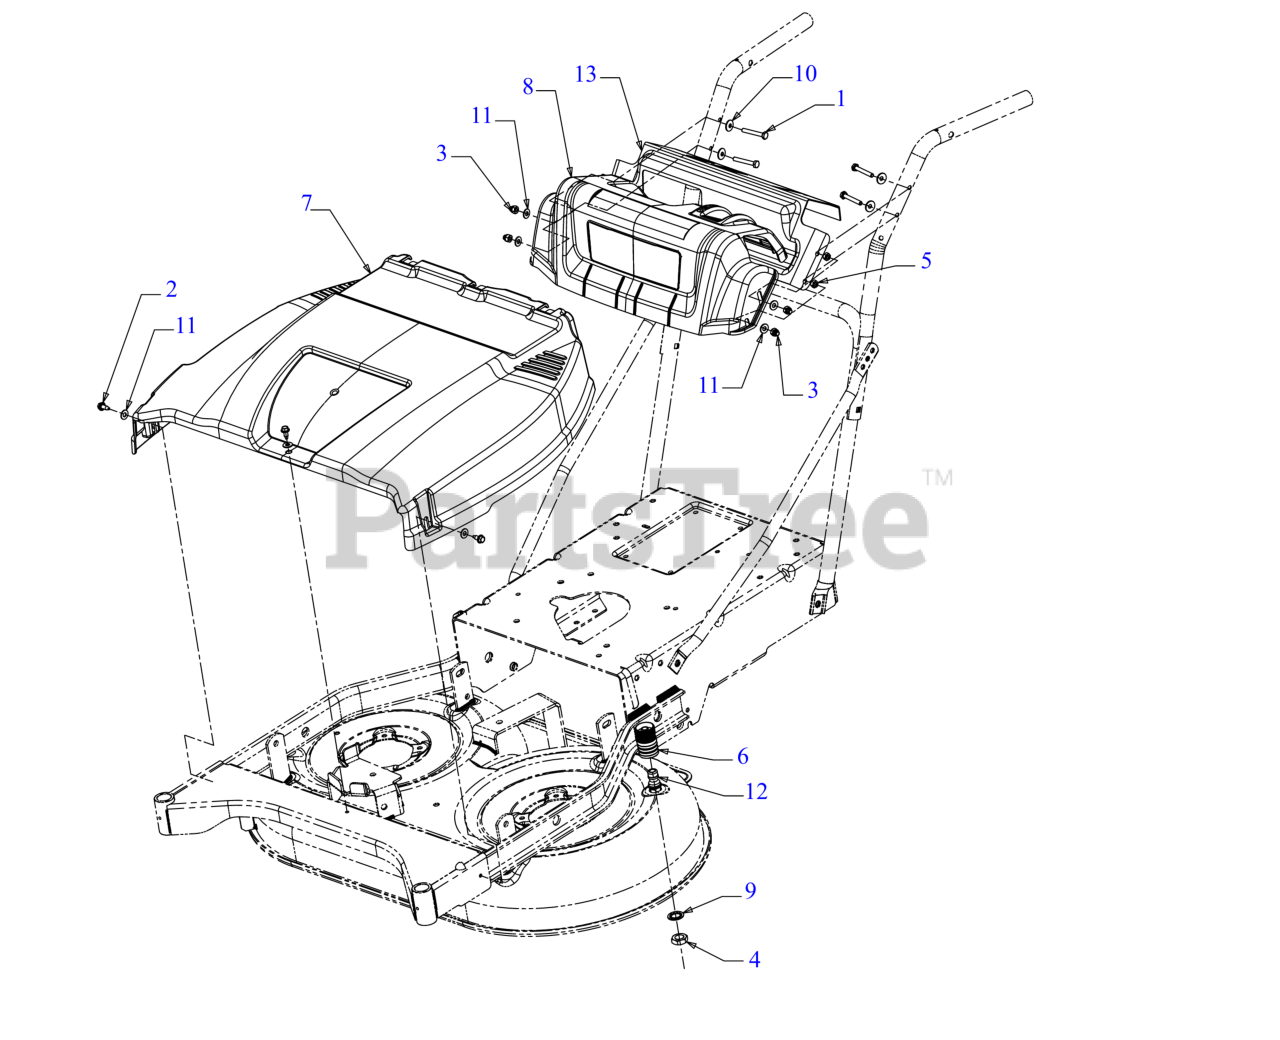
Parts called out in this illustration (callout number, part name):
1	HEX SCREW 1/4-20 x 1.75
2	SCREW 1/4-14 x .625
3	HEX ACORN NUT
4	HEX NUT
6	WATER NOZZLE ADAPTER
7	WIDECUT BELT COVER
8	HANDLE PANEL COVER
9	LOCK WASHER 5/8
10	SPRING WASHER BELL
11	FLAT WASHER
12	DECK WASH NOZZLE
